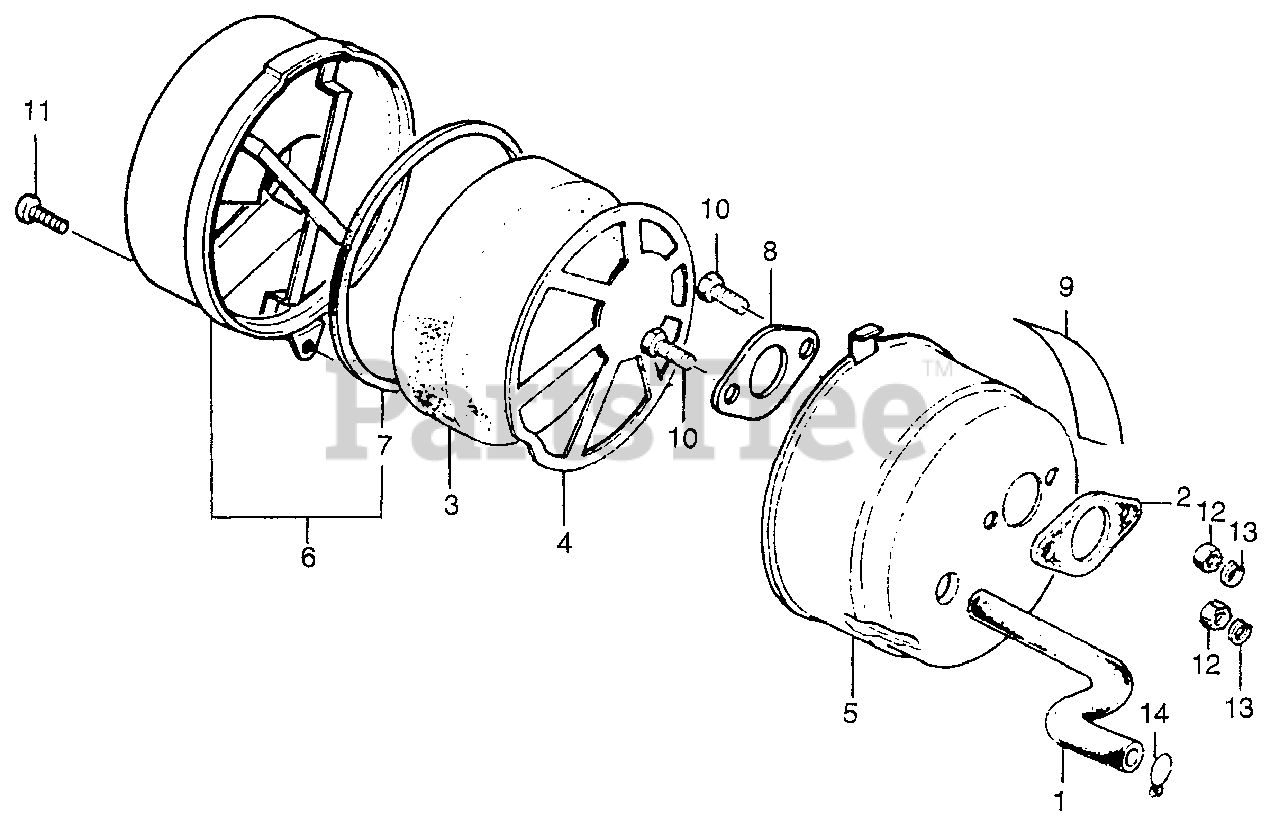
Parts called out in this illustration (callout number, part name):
1	TUBE, BREATHER (NOT AVAILABLE)
2	GASKET, AIR CLEANER (NOT AVAILABLE)
3	ELEMENT, AIR CLEANER
4	GRID, CLEANER (NOT AVAILABLE)
5	HOUSING, AIR CLEANER *R8* (BRIGHT RED) (NOT AVAILABLE)
6	COVER, AIR CLEANER *R8* (BRIGHT RED) (NOT AVAILABLE)
7	RUBBER, SEAL (NOT AVAILABLE)
9	LABEL, AIR CLEANER CAUTION
10	BOLT, HEX. (6X12)
14	CLIP, TUBE (B12.5)
